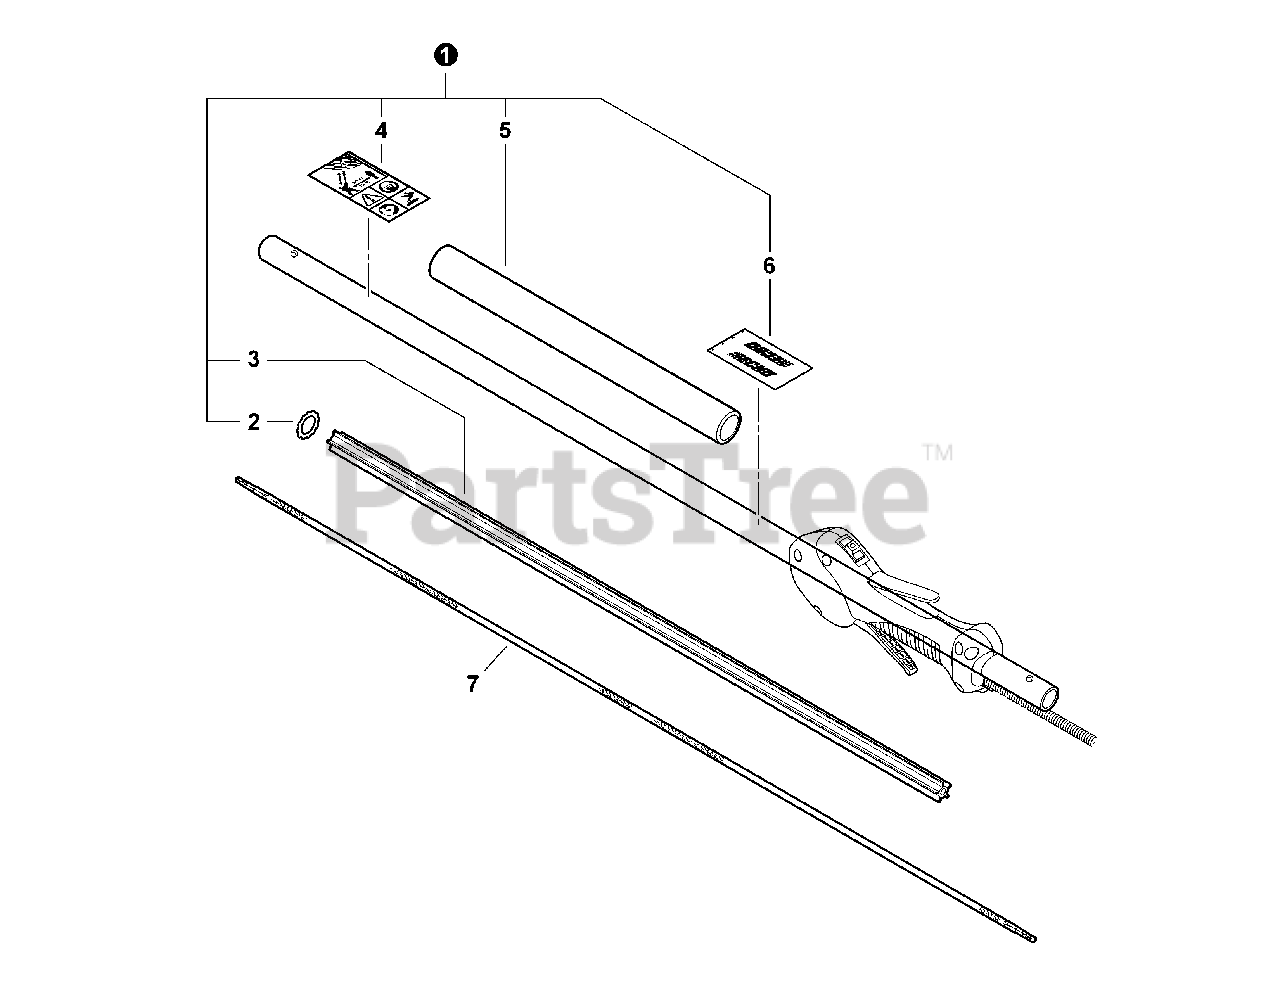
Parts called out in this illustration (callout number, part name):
1	MAIN PIPE ASY
2	LOCKWASHER - EXTERNAL
3	LINER - FLEXIBLE
4	LABEL - CAUTION
5	GRIP, FRONT
6	LABEL - HANDLE LOCATION
7	DRIVESHAFT - FLEXIBLE
